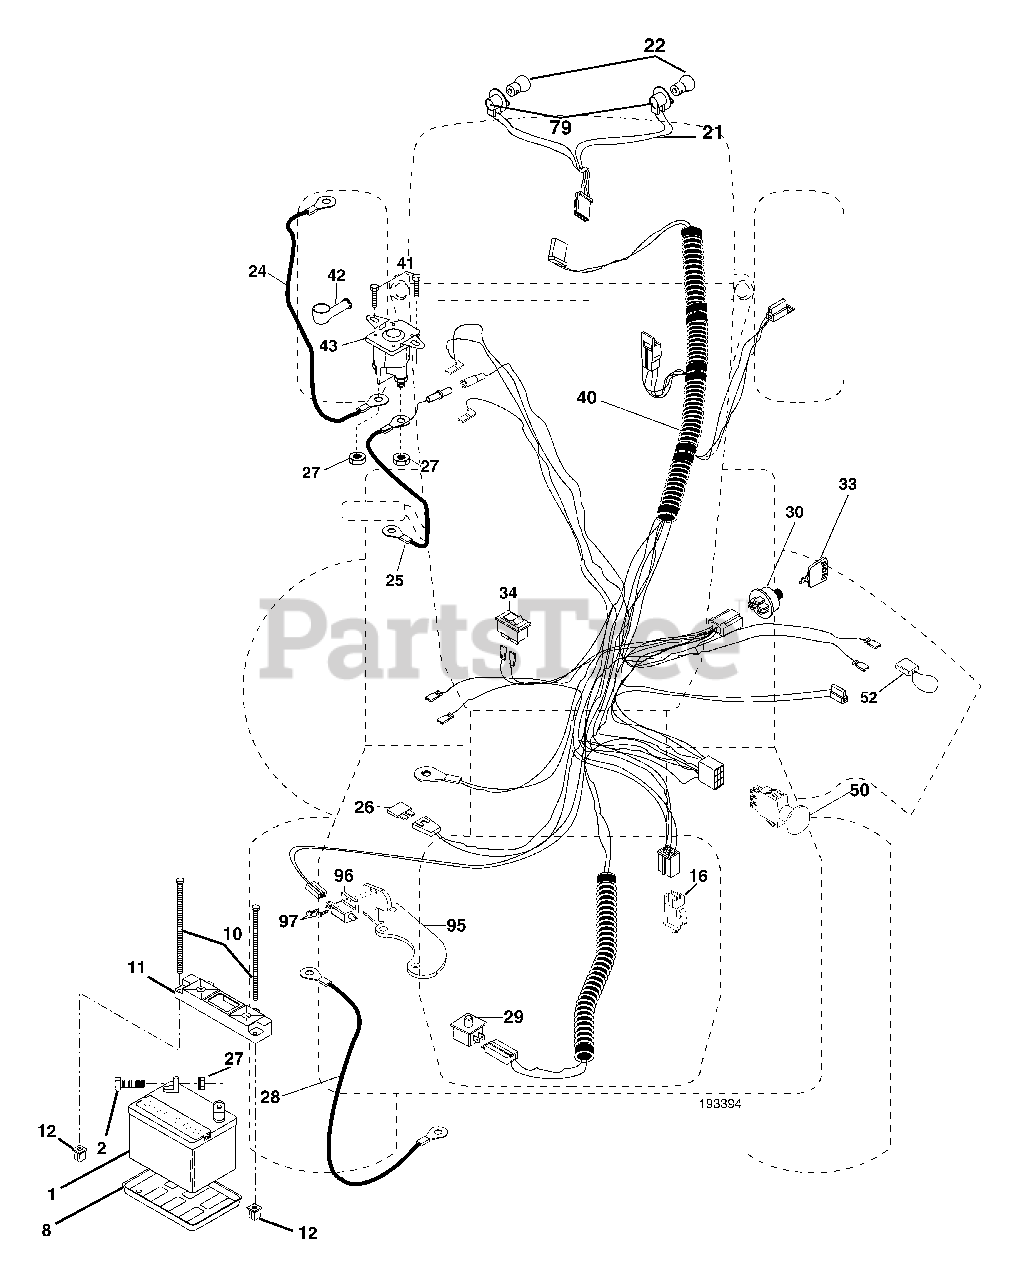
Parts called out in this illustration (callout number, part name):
1	Battery
2	Bolt Hex Head 1/4-20 x 3/4
8	Tray, Battery
10	Bolt, Battery Front 1/4-20 x 7.5 Zinc
11	Holddown Battery Front Mount
12	Nut, Push Nylon 1.4" Battery Front
16	Switch Interlock Push-In
21	Harness Socket Light w/4152J
22	Bulb Light
24	Cable Starter
27	Nut Keps Hex 1/4-20
28	Cable Bolt Ground
29	Switch, Seat
30	Switch, Ign
34	Switch Light/Reset B/B/Red
40	Harness Ign.
41	Screw Thd Cut 1/4-20 x 1/2
42	Cover, Terminal Red
43	Solenoid
50	Switch, PTO
52	Protection Wire Loop
79	Bulbholder Asm
95	Bracket ROS
96	Switch Intek
97	Screw Hex Wsh SLT #10-24 x .50
